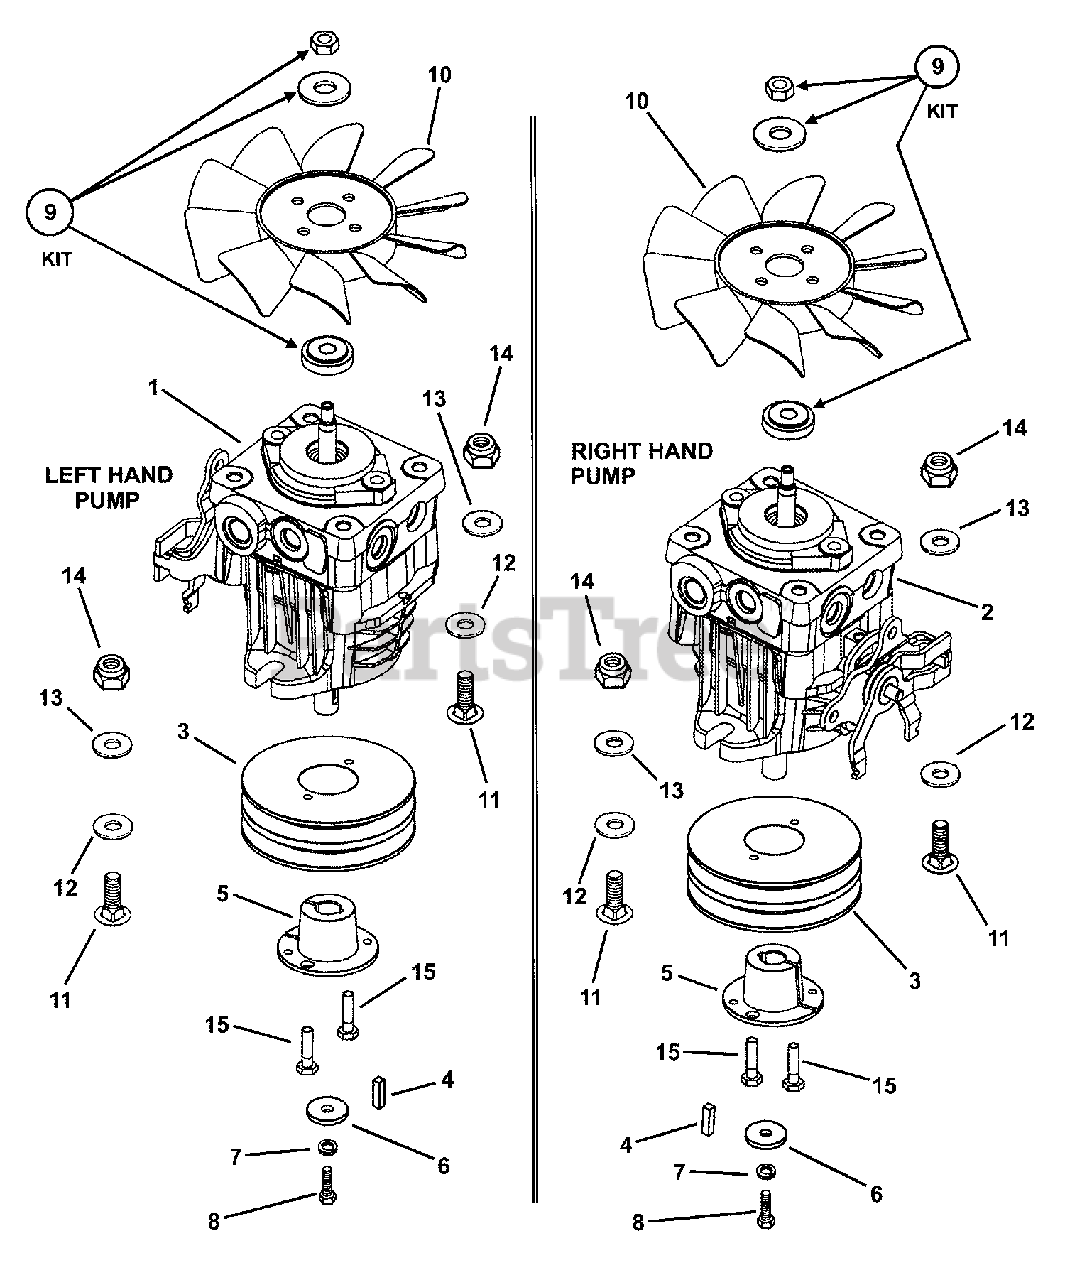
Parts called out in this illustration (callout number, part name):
1	PUMP, Hydro-Gear (Left Hand)
2	PUMP, Hydro-Gear (Right Hand)
3	PULLEY, 4.25 O.D. x 1.375 OA x "H" Tapered Bore
4	KEY, M5 x M20
5	PULLEY, "D" Bushing x 15mm Bore
6	WASHER, 1/4 x 1x 1/8" Flat
7	WASHER, 1/4" Split Lock
8	SCREW, M6 1.0X12MM, Hex Head, CZ
9	KIT, Fan Hub (Includes 1 each of 3 items shown below)
10	FAN, 7" Nylon, Counter-Clockwise
11	BOLT, 3/8-16 x 1-1/4" Short Neck Carriage GR 5
12	RETAINER, 3/8" Bolt
13	WASHER, 3/8" Flat
14	NUT, 3/8-16 HEX NYLON LOCK
15	BOLT, 1/4-20 X 1" GD5 CZ
